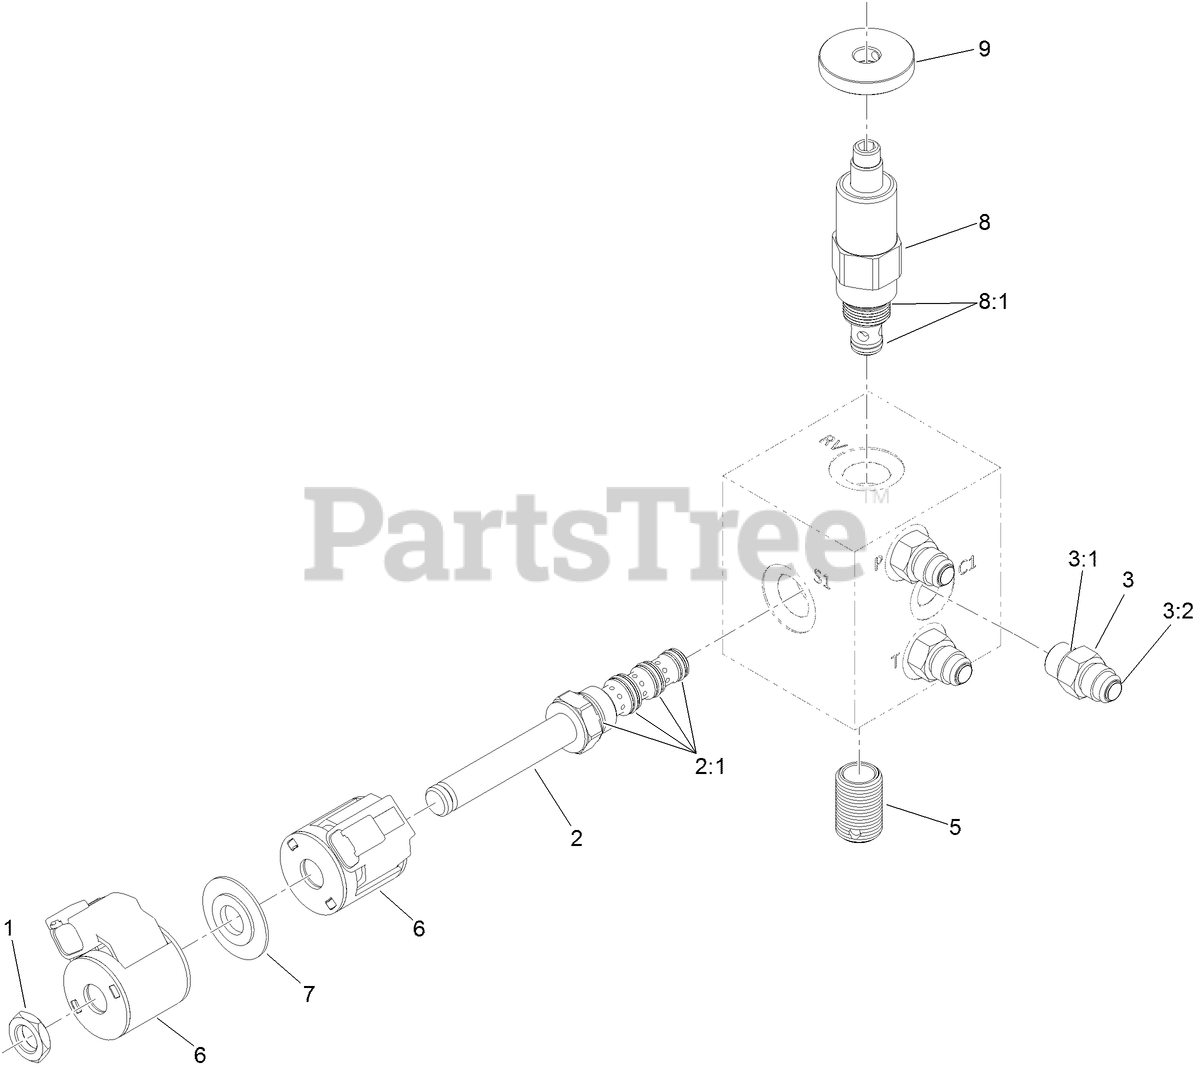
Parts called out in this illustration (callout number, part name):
1	NUT-COIL
2	VALVE-SOLENOID
2:1	SEAL KIT
3	FITTING-STRAIGHT
3:1	O-Ring
3:2	O-RING
5	NIPPLE-FILTER
6	COIL-SOLENOID
7	SPACER-COIL
8	VALVE-RELIEF, POPPET TYPE
8:1	SEAL KIT
9	KNOB (1.5 DIA)
